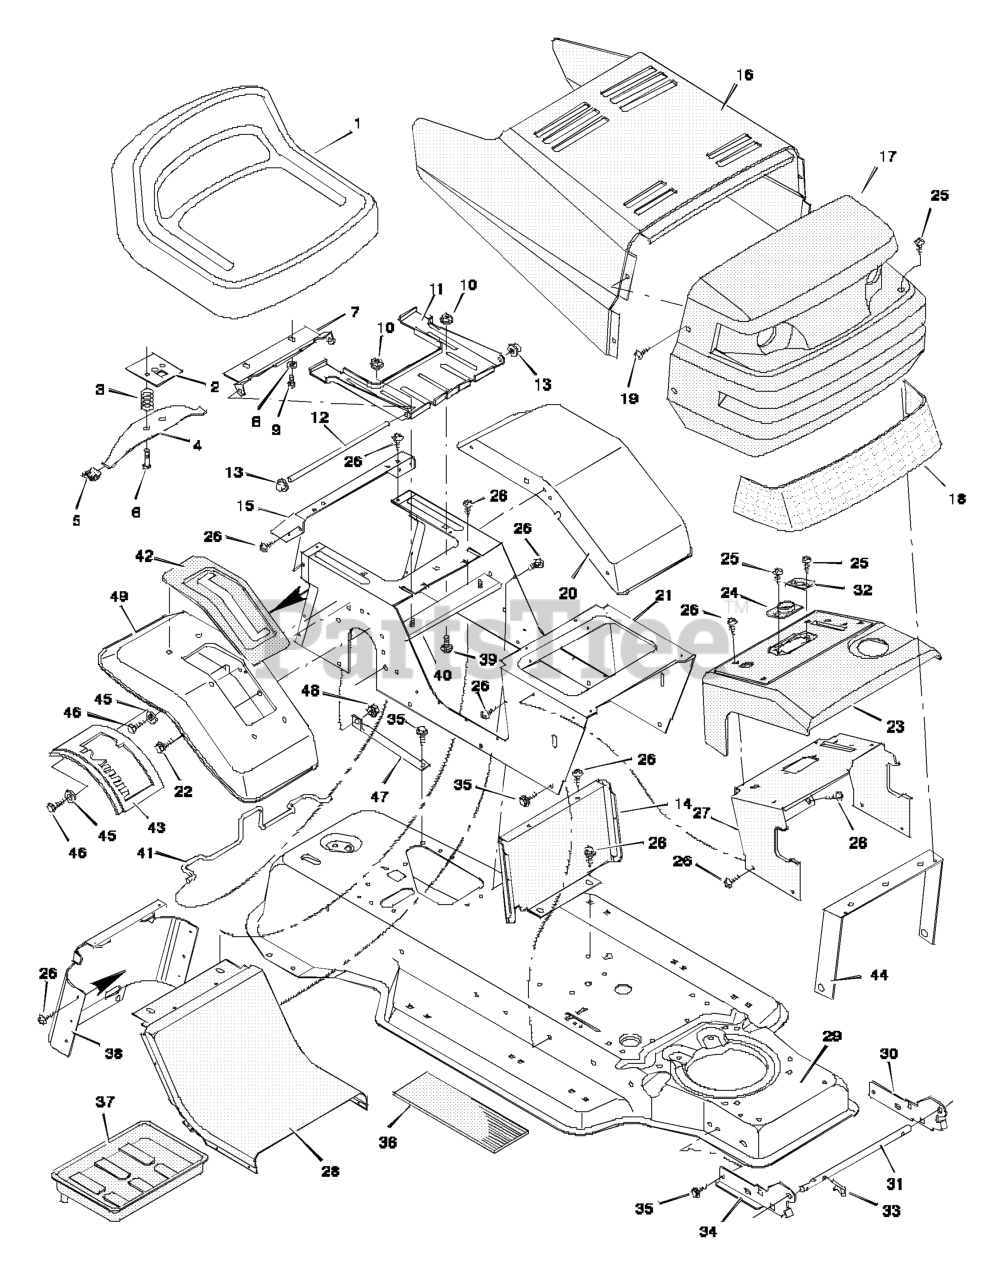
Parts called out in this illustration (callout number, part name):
2	Plate Assembly, Switch
3	Spring, Compression
4	Spring, Seat
5	Glide, Spring
6	Bolt, Shoulder
7	Support, Seat
8	Lockwasher
9	Bolt, Hex
10	Locknut, Flange
11	Bracket, Pivot
12	Rod, Pivot
13	Cap, Push On
14	Insert, Front
15	Fender, Apron
17	Grille Assembly
21	Console Assembly
23	Dash Panel
24	Bearing, Steering
26	Screw
27	Support, Dash
28	Insert, Rear
29	Frame Assembly
30	Bracket, Left Grille
31	Rod, Pivot
32	Bearing
33	Pin, Hair
34	Bracket, Right Grille
37	Tray, Battery
38	Cap, Console
39	Bolt
40	Channel Assembly
41	Clamp, Battery
42	Cover, Shift
43	Gate, Shift
44	Brace, Grille
46	Bolt, Hex
47	Strut, Shifter
48	Locknut
49	Fender, SOG
